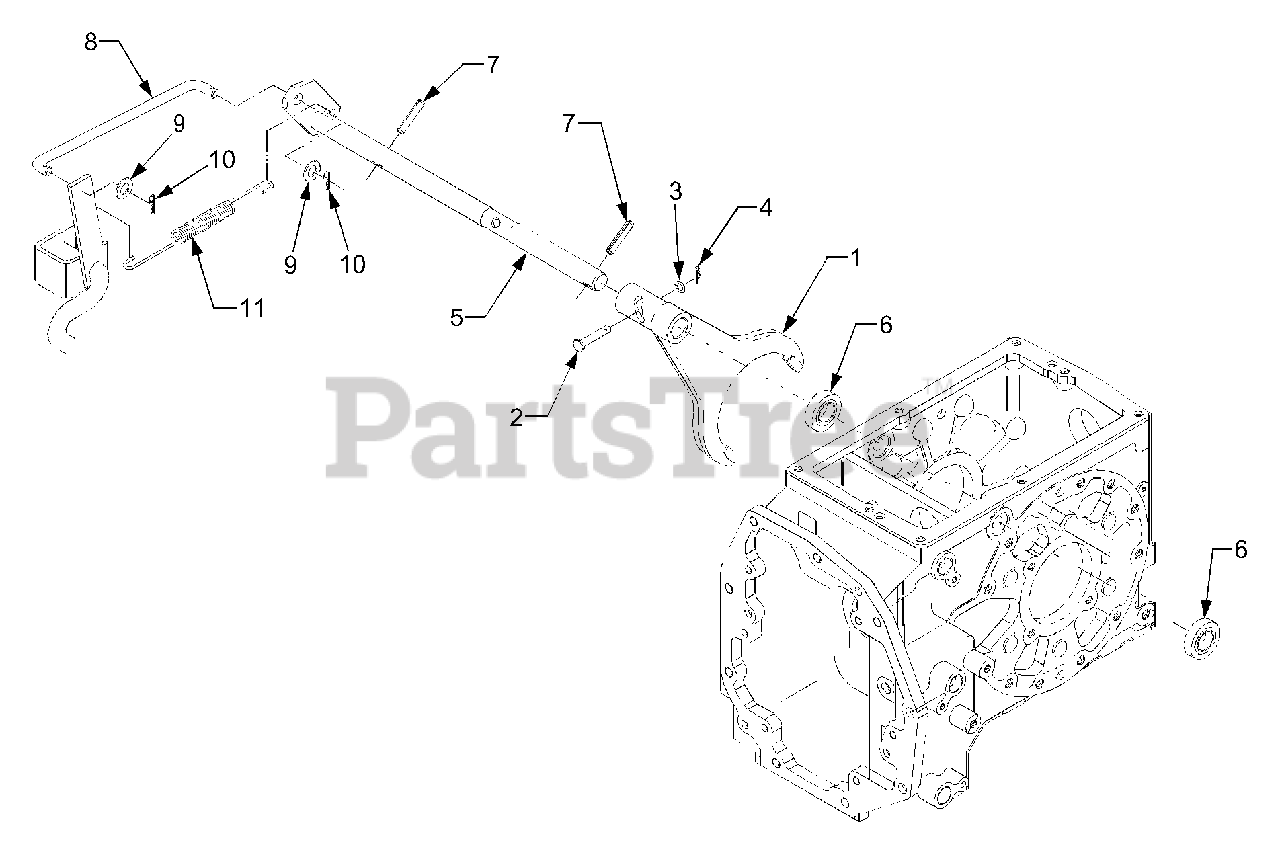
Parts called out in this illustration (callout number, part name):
1	Fork, Differential Lock
3	Washer, Plain
5	Shaft, Differential Lock
8	Rod, Differential Lock
9	Washer, Plain
